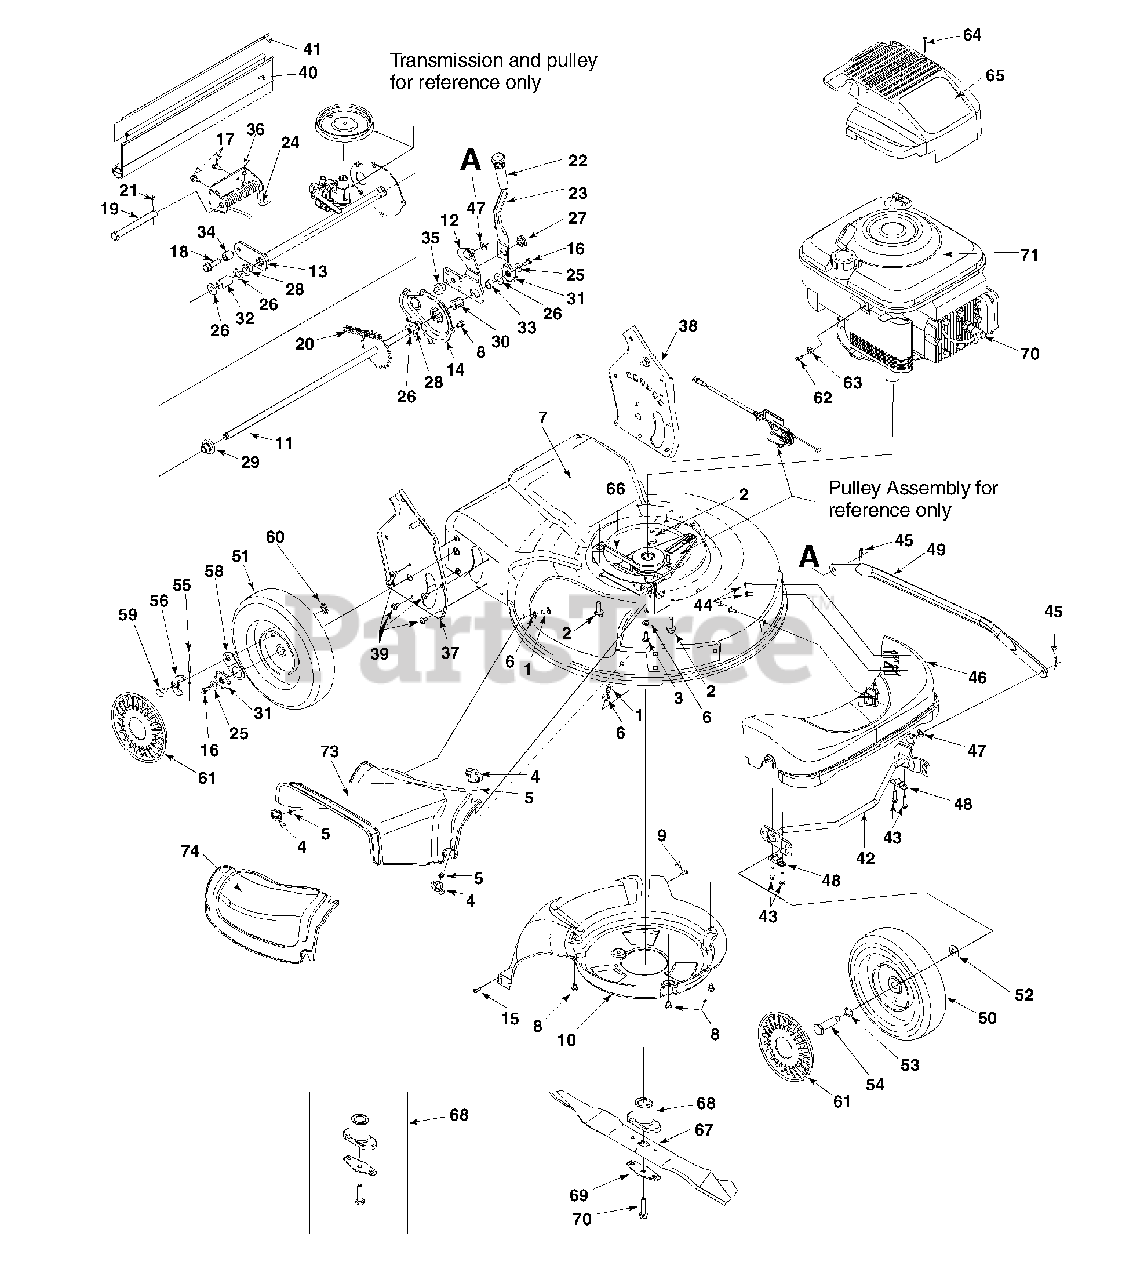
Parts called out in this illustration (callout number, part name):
1	Scr. Carr. 1/4-20 x .62
2	Scr. TT:3/8-18:1.00
3	Scr. 1/4-20 x .750
4	Wing Nut 1/4-20
5	Nut, Push .25 I.D. x .50 O.D.
6	Wash. Fl. .334 I.D.x .62 x.03
7	Deck - 21"
8	Scr. TT. 1/4-20 x .375
10	Baffle
11	Rear Axle Ass'y
16	Cap Screw HH 1/4-20 x .620
17	Scr., AB 1/4-14 x .825
18	Scr., 3/8 116 x .25
19	Clevis Pin .50 Dia. x 4.82 Lg.
20	Chain-Endls. #48 .500P x 24L
21	Cotter Pin .125 O.D. x .75
23	Spring Lever
24	Torsion Spring
25	Bell Wash. .285 x .75 x .082
26	Fl. Wash..508 I.D. 1.000 x.020
27	Nut Shld. .825 Dia. x .165 Lg.
28	Hx.Flg. Brg..506 I.D. x .590 L.
29	Hx.Flg. Brg. .506 I.D. x.715 L.
30	Hx. Slv. Brg..504 I.D. x .830 L.
31	Wheel Rachet
32	Spa. .550 I.D. x /750 O.D.
33	Spa. .51 .D. x .70 O.D. x 38 L.
34	Spa. .385 x .624 x .700
35	Shld. Spa. .385 I.D. X .715 Lg.
38	Handle Brkt. Assembly L.H.
39	Scr. AB 1/4-14 x .500
40	Trail Shield
41	Trail Shield Wire
42	Fr. Axle Ass'y.
43	Hx Scr. Wash Hd. Hi.-Lo.
44	Scr. Torx, Truss Hi.-Lo.
45	Cotter Pin .072 x 1.12 Lg.
46	Fr. Axle Cover
47	Bowed Washer
48	Bush. Block .505 Dia. x .62
49	Control Arm
50	Wheel 7 x 2 Link Black
51	Wheel 9 x 2 Link Beige, Sleeve
52	Spr. Wash. .401 x .870 x .063
53	Wave Wash .510 x .750 x .017
54	Shldr Scr .498 x 1.445 x 3/8-16
55	Spring, Ratchet, Plastic
56	Pawl - R.H.
58	Ratchet Pawl Plate
60	Top Lock Tab Weld Nut 1/4-20
61	Hubcap
62	Screw .620 Hx. Slt. Wsh.
63	Casing Clamp, Throttle
64	Scr. Hi-Lo #10 x 1.25
66	Belt
67	21" Mulching Blade
68	Blade Adapter Kit
69	Blade Bell Support
70	Hex Bolt 3/8-24 x 2.5" Lg.
71	Engine
73	Side Discharge Chute
74	Mulch Cover
